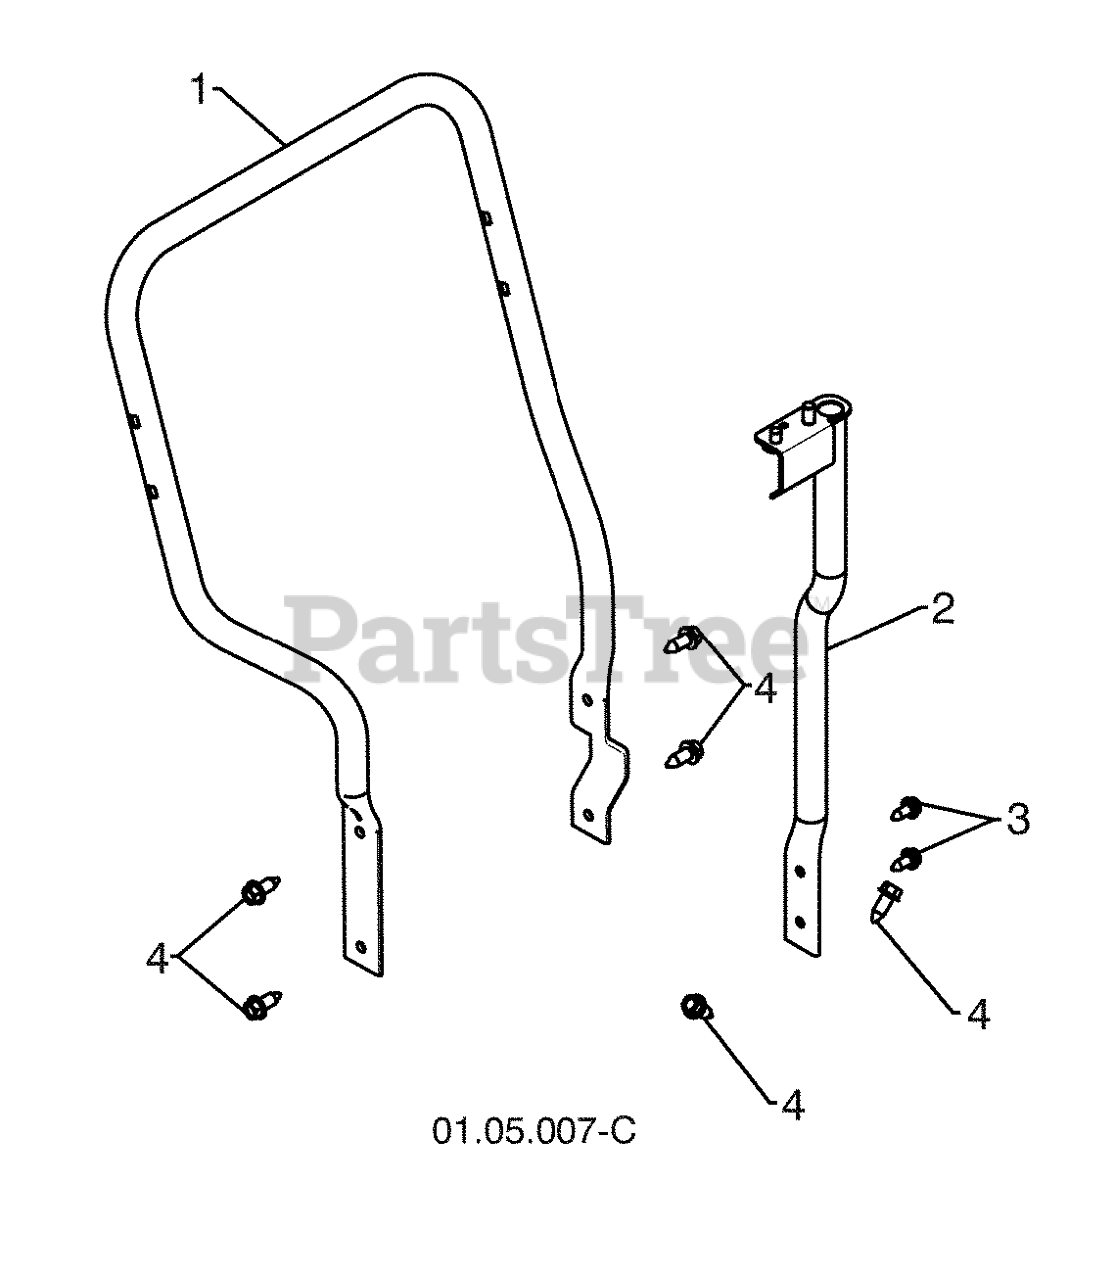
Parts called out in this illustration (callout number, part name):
1	TUBE.LOWER.HANDLE.SNOW.GRAY
2	SUPPORT.WELDMENT.ROTATOR.
3	BOLT.HEX.HD.WASHER.5/16-18X.75
4	SCREW 3/8-16X1
